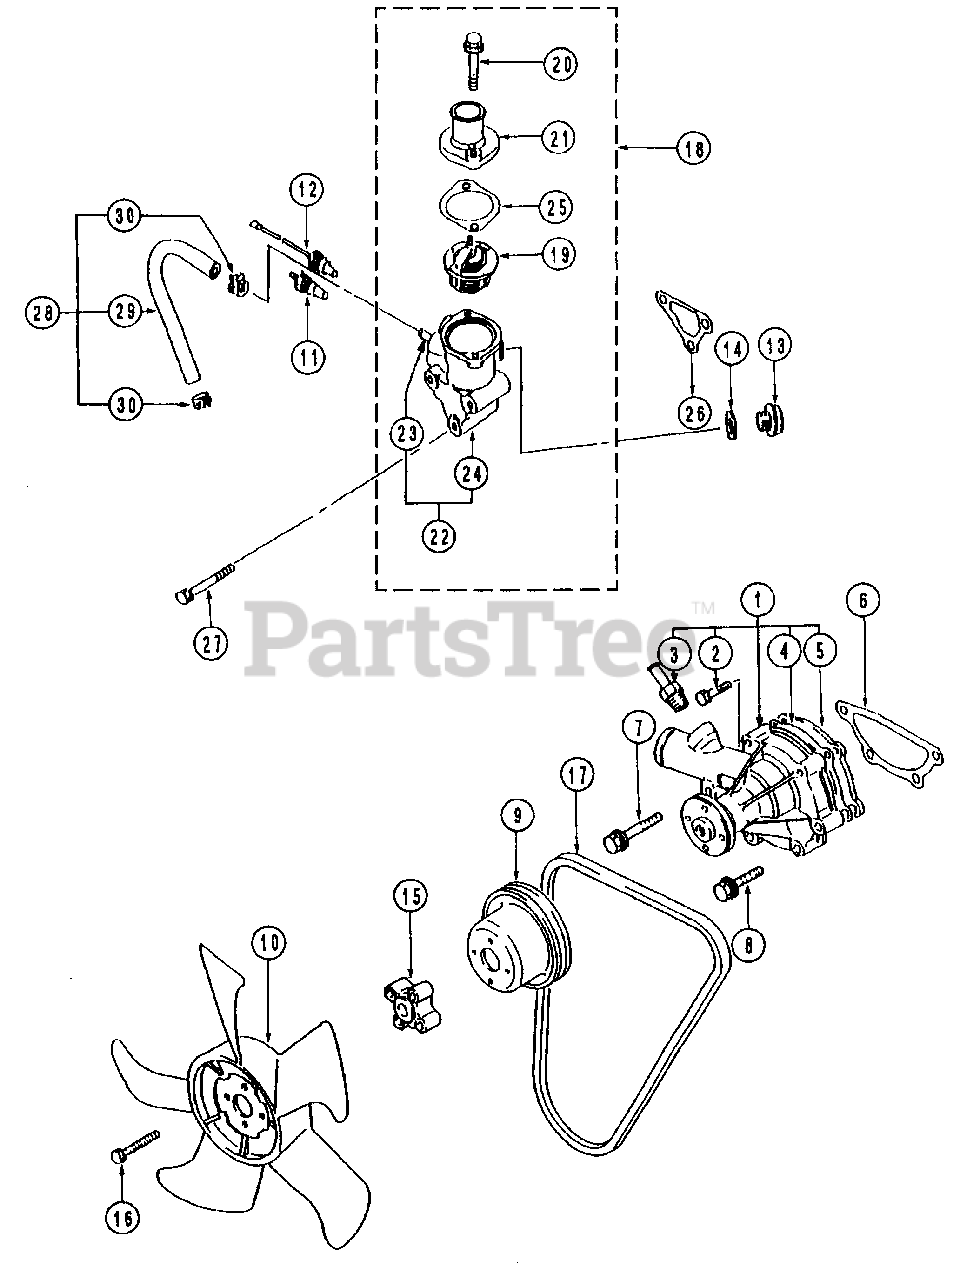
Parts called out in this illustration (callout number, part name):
1	Pump Ass'y., Water
2	Bolt, W/Washer
6	Gasket, Water Pump
7	Bolt, W/Washer
8	Bolt, W/Washer
9	Pulley, W/Pump 89
10	Fan, Cooling
11	Gauge, Unit Water
12	Switch Ass'y., Thermo.
13	Plug, Drain
15	Spacer, Fan
16	Bolt, W/Washer
18	Thermostat Ass'y.
20	Bolt, Flange
21	Cover, Thermostat
22	Case Ass'y., Thermostat
23	Pipe, Thermostat
24	Case, Thermostat
25	Gasket, Thermostat
26	Gasket, Thermo.Case
27	Bolt, W/Washer
28	Hose Ass'y, Fuel
29	Hose, Fuel
